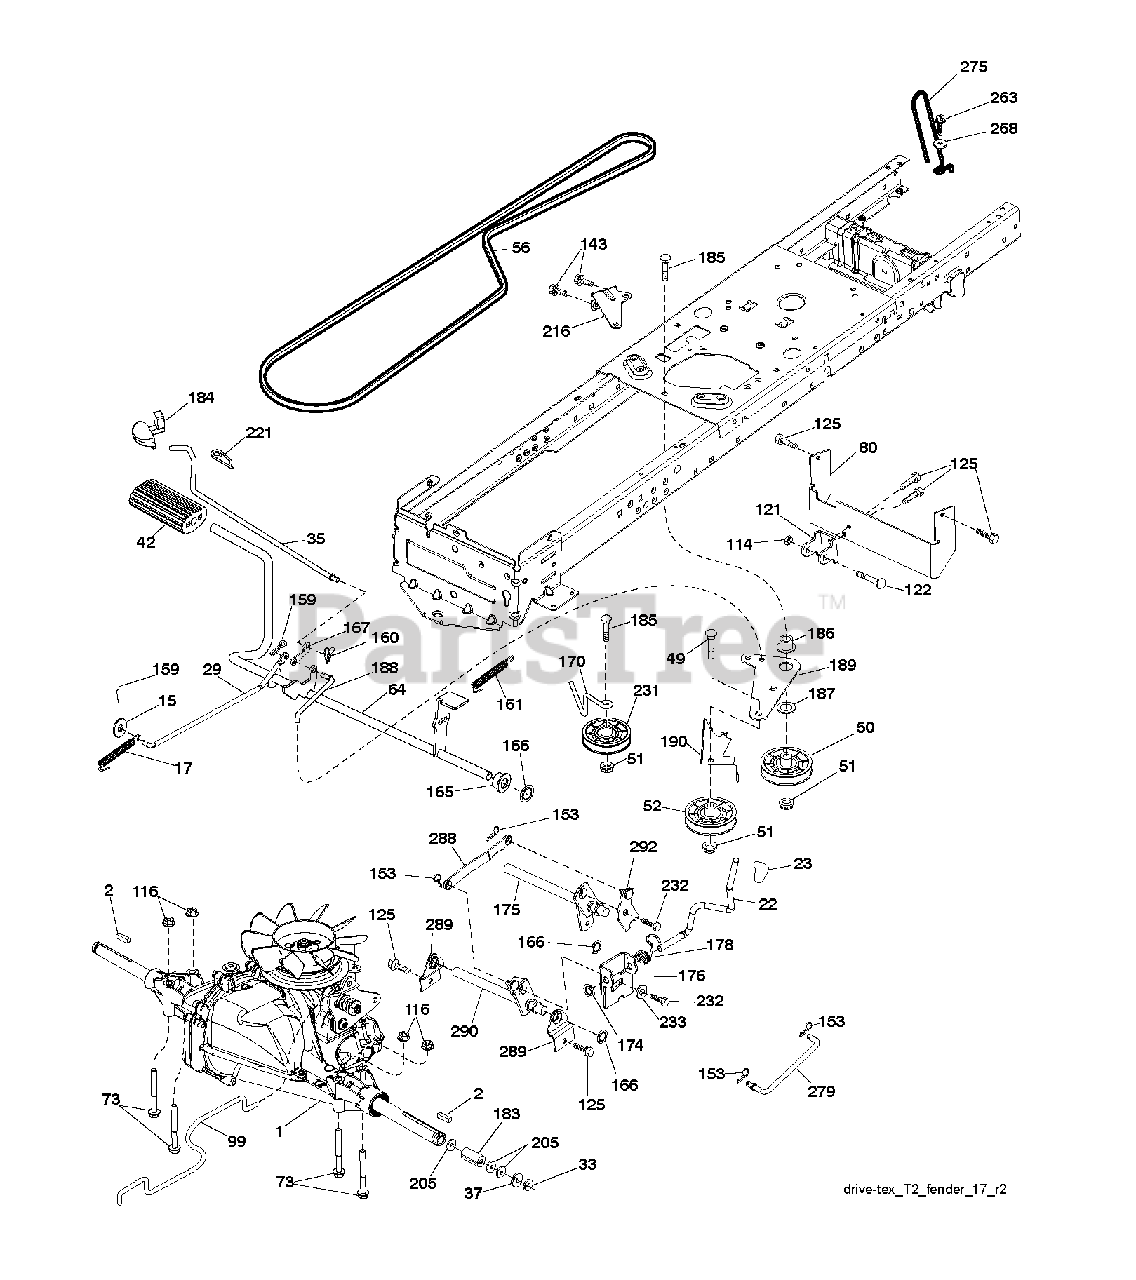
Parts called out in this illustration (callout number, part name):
17	SPRING.BRAKE.HG3000/3500
22	SHIFTER.ASM.HANDLE.SRD
23	KNOB.DUCKHEAD.1/2
35	ROD.BRAKE.PARKING.LT.T
42	PEDAL COVER T
49	BOLT
50	IDLER.FLAT.910.OFFSET
51	NUT LOCK FLG 3/8-16 UNC
52	IDLER.V-GROOVE.910.OFFSET
64	SHAFT.ASM.PEDAL.BRAKE.
73	BOLT HEX 5/16-18 GR 5
80	STRAP.TORQUE.FS.T2
99	ROD.ASM.BYPASS.SPRING.T2.FS
114	NUT.71038.31-18.HEX.NYLOCK
116	NUT LOCK HEX FLANGE 5/16-18
121	BRACKET STRAP TORQUE
122	BOLT.5/16-18X2.5
125	SCREW
153	RETAINER M
159	COTTER PIN
160	RETAINER CLIP
161	SPRING, RETURN LT
165	BUSHING.SHAFT.BRAKE.HAND
167	LATCH.BRAKE.SPRING
170	KEEPER.CENTER SPAN.1.688
174	NUT.PUSH.500.2006
175	SHAFT.ASM.SHFT.T2.TLT
176	ARM.CLEVIS.ROD.SHIFT
178	SPRING.TORSION.LIFT.HANDLE
183	SPACER, AXLE PVST
184	HANDLE.PAKRING.BRAKE.
186	SPACER.RETAINER
187	WASHER 12/32X2X10GA
188	LINK.CLUTCH.GROUND.DRIVE
189	BELLCRANK.GROUND.DRIVE.TEX.
190	KEEPER.BELLCRANK.DRIVE
216	BRACKET.PULLEY.IDLER.W/TEX
221	RETAINER.SPRING.CLIP.H
231	IDLER.V-GROOVE.1.688.OFFSET
232	BOLT FIN HEX 7/16-14 X 1
233	WASHER SERRATED
263	SCREW, 3/8-16X3/4
268	WASHER
279	LINK.SHIFT.T2
288	LINK.SHIFT.SLAVE.SRD
289	BRACKET.SUPPORT.SHIFT.OUTER
290	SHAFT.ASM.SHIFT.REAR.SRD
292	PLATE.ASM.SHIFT.FWD.SRD
